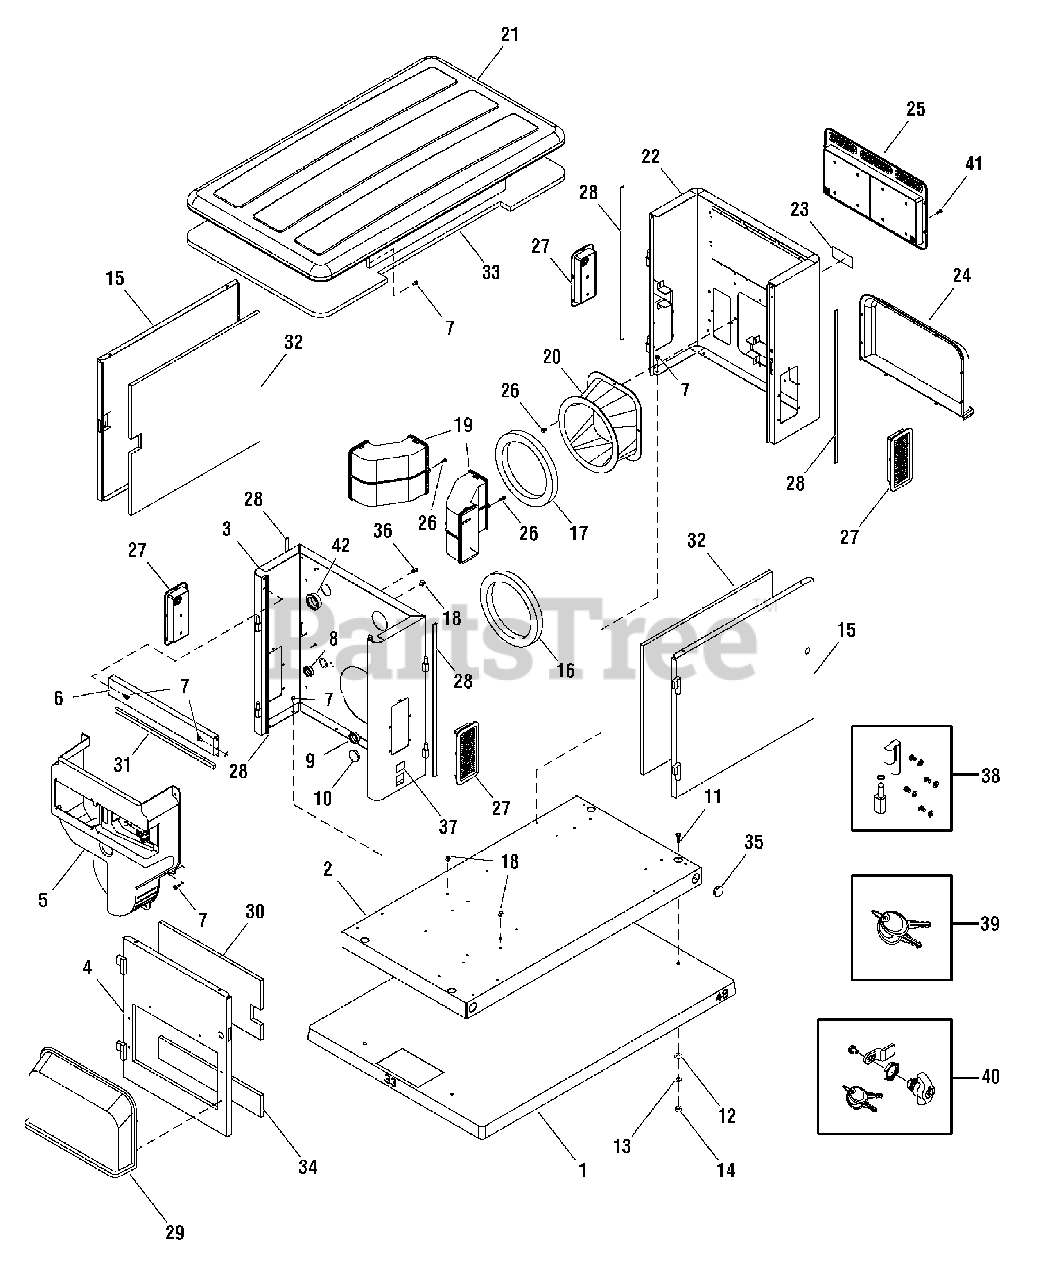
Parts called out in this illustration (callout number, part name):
2	BASE
3	BULKHEAD ASSEMBLY, Engine End
4	DOOR ASSEMBLY, Engine. End
5	DUCT ASSEMBLY, Engine Air
6	SUPPORT RAIL ASSEMBLY
7	CAPSCREW, Hex Head, Trilobular, 1/4-20 x 1/2
8	BUSHING, Snap, 1-3/8"
9	BUSHING, Snap, 1-1/2"
10	Plug, Dome, 1-1/2"
11	*CAPSCREW, Hex Head, 3/8 - 16 x 1
12	*WASHER,, Flat, 3/8 - M10
13	*WASHER, Lock 3/8
14	*NUT, 3/8 - 16
17	SEAL, Foam, Alternator Air
18	MOUNT, Tie Wrap
19	DUCT, Rubber Alternator
20	ADAPTER, Alternator
22	BULKHEAD ASSEMBLY, Alternator End
23	DECAL, Caution Hot Muffler
24	COVER, Air Intake Alternator
29	COVER, Air Intake Engine
30	INSULATION, Engine Door, Top
32	INSULATION, Front/Rear Door
34	INSULATION, Engine Door, Bottom
37	DECAL
38	KIT, Door, Hinge
41	SCREW
